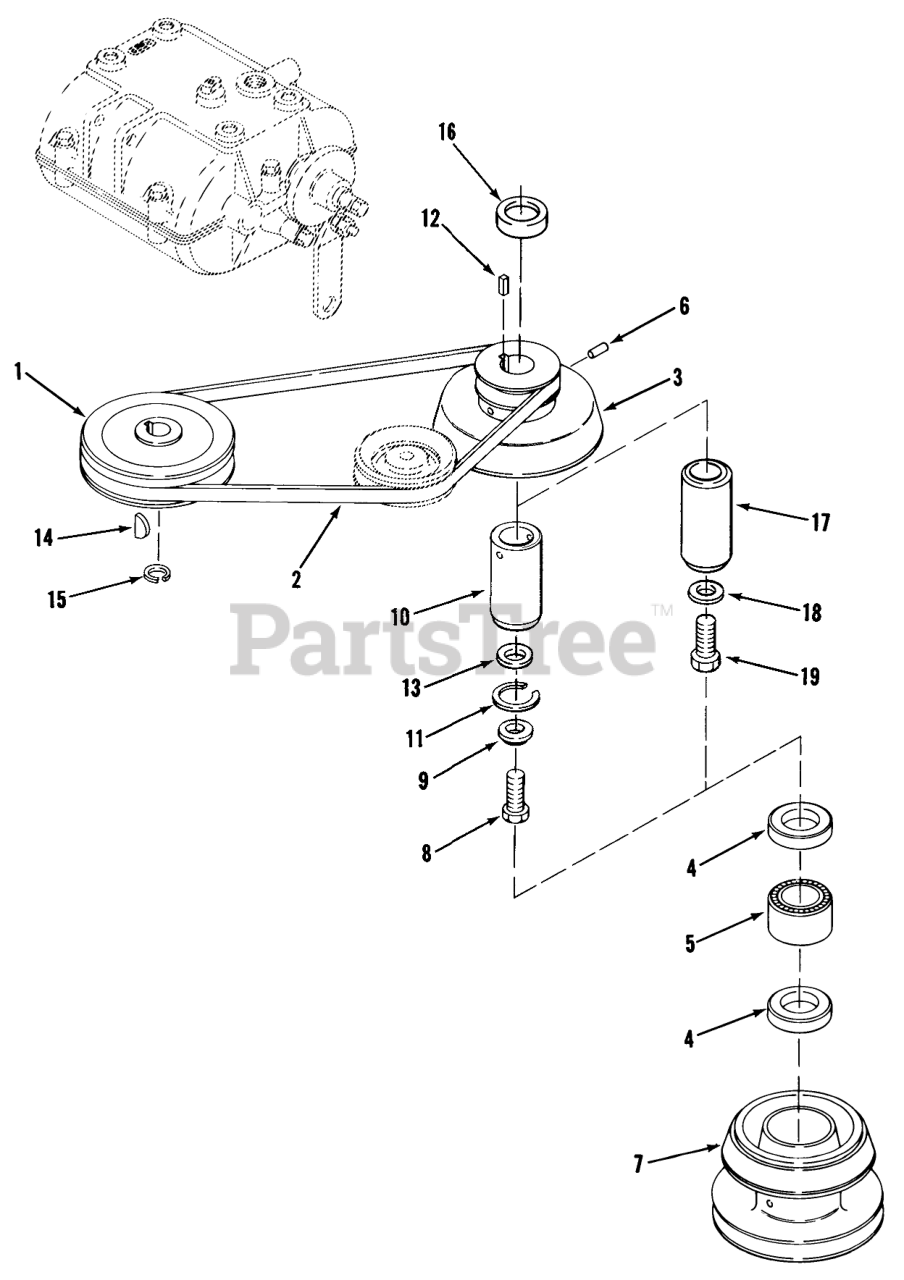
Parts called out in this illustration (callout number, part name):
1	PULLEY
4	SEAL-OIL
5	BRG-NEEDLE OPEN END
6	SPIROL PIN 3/16X9/16
11	RETAIN RING
12	KEY-SQUARE
13	SHIM-WASHER
15	SNAP RING- 5/8 EXT
19	HEX HD CAP SCREW
